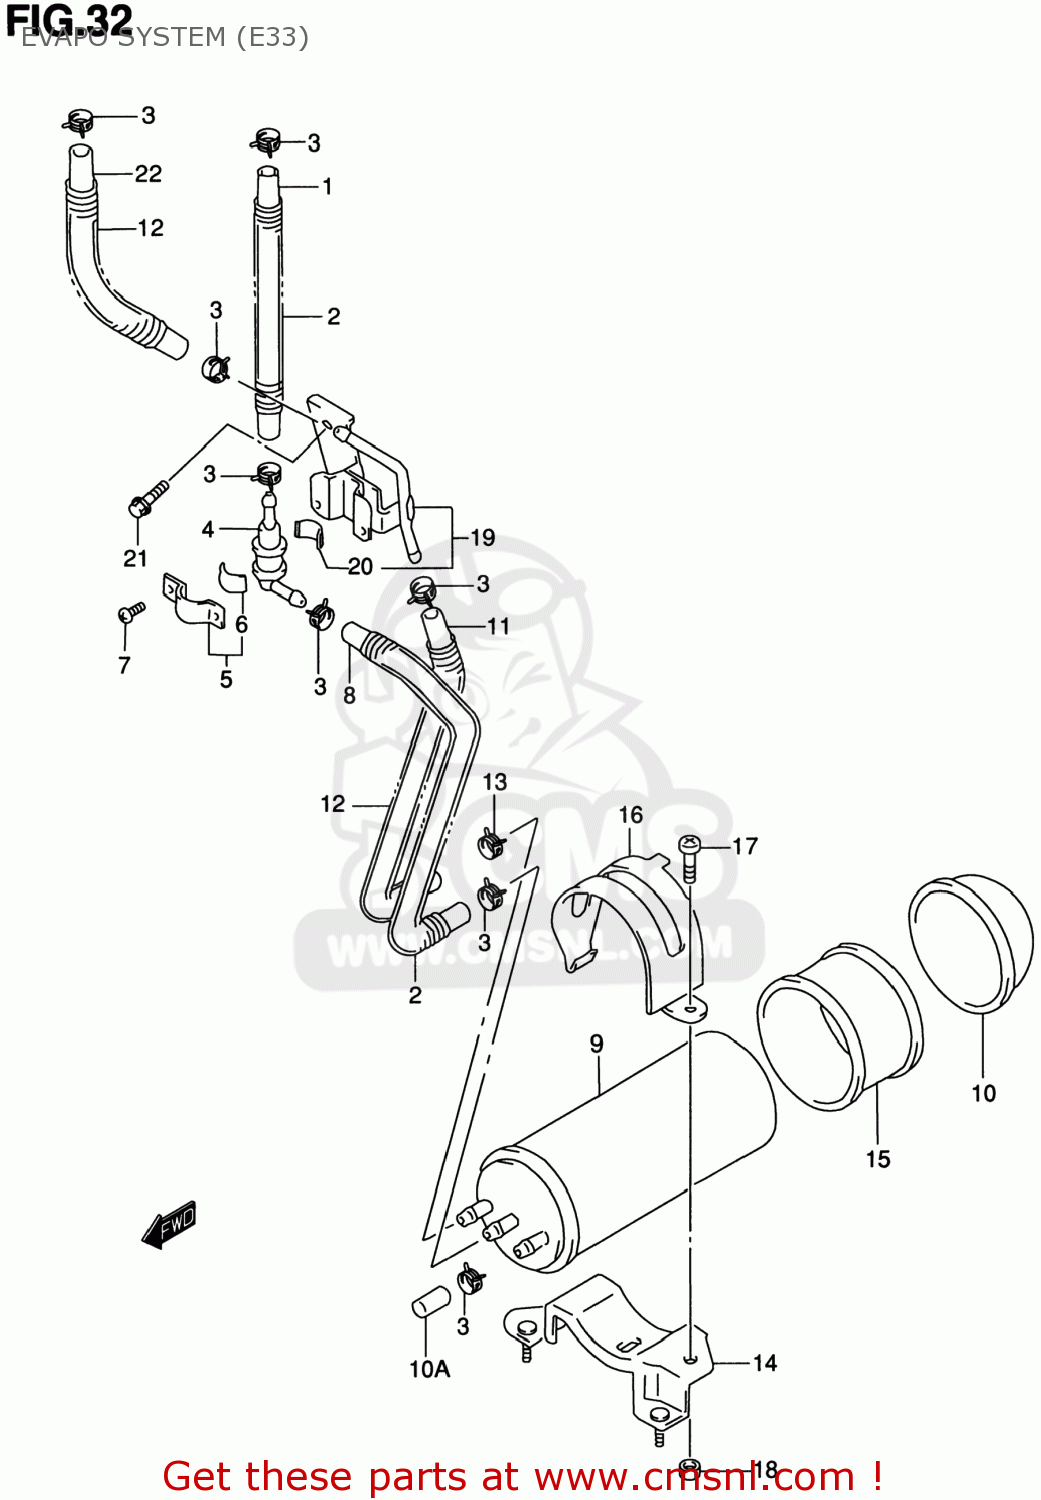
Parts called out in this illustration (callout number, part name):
1	HOSE(5.4X11.4X600)
2	SPRING
3	CLIP
4	VALVE,FUEL TANK BREATHER
5	PLATE,FUEL TANK BREATHER NO.2
6	CUSHION
7	SCREW
8	HOSE,BREATHER VALVE & CANISTER
9	CANISTER ASSY,CHARCOAL
10	CAP,CANISTER
10A	CAP,OD:11.5
11	HOSE,CSTR & CARB NO.1
12	SPRING
13	CLIP
14	BRACKET,CANISTER
15	CUSHION,CANISTER
16	HOLDER,CANISTER
17	SCREW 6X12
18	NUT
19	BRACKET,FUEL TANK BREATHER
20	CUSHION
21	BOLT
22	HOSE(5.4X11.4X600)
